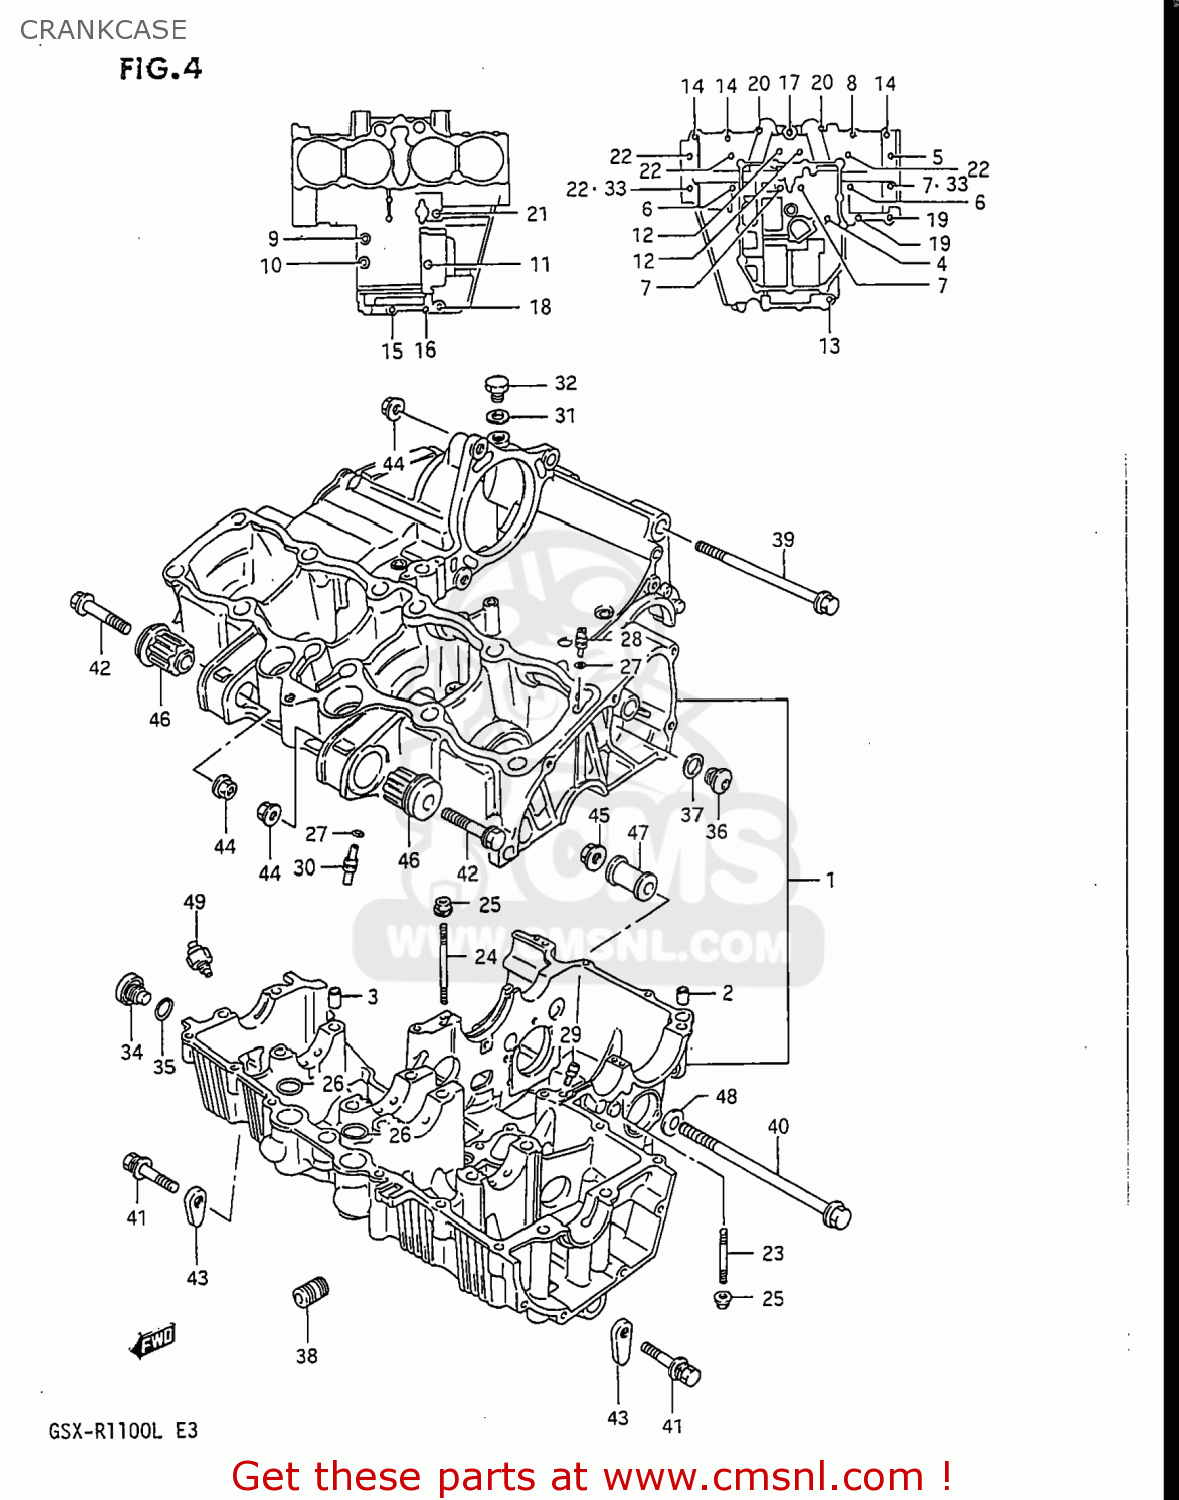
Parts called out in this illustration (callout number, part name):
1	CRANKCASE SET
2	PIN(10.4X13X22)
3	PIN (11X20)(SUS)
4	BOLT(6X105)
5	BOLT(8X105)
6	BOLT(8X125)
7	BOLT(8X115)
8	BOLT 6X35
9	BOLT
10	BOLT
11	BOLT
12	BOLT
13	BOLT 8X60
14	BOLT 6X35
15	BOLT
16	BOLT
17	BOLT 6X50
18	BOLT ,6X60
19	BOLT
20	BOLT
21	BOLT
22	BOLT(8X95)
23	STUD BOLT
24	STUD BOLT
25	NUT
26	O RING(D:2.5,ID:21)
27	O RING(D:1.2,ID:4)
28	JET,AIR
29	JET
30	JET,OIL GALLERY
31	GASKET(12.1X16.2X3.7) (NAS)
32	PLUG(12X9)
33	GASKET(8.5X17X2.3) (NAS)
34	PLUG
35	O RING(D:2.4,ID:16.8)
36	PLUG
37	GASKET(14X19.2X2) (NAS)
38	UNION,OIL STAND
39	BOLT 10X150
40	BOLT(12X178)
41	BOLT
42	BOLT 10X55
43	NUT
44	NUT
45	NUT 12MM
46	BUSH,ENGINE MOUNTING
47	SPACER,ENGINE MOUNT
48	WASHER
49	SWITCH ASSEMBLY
